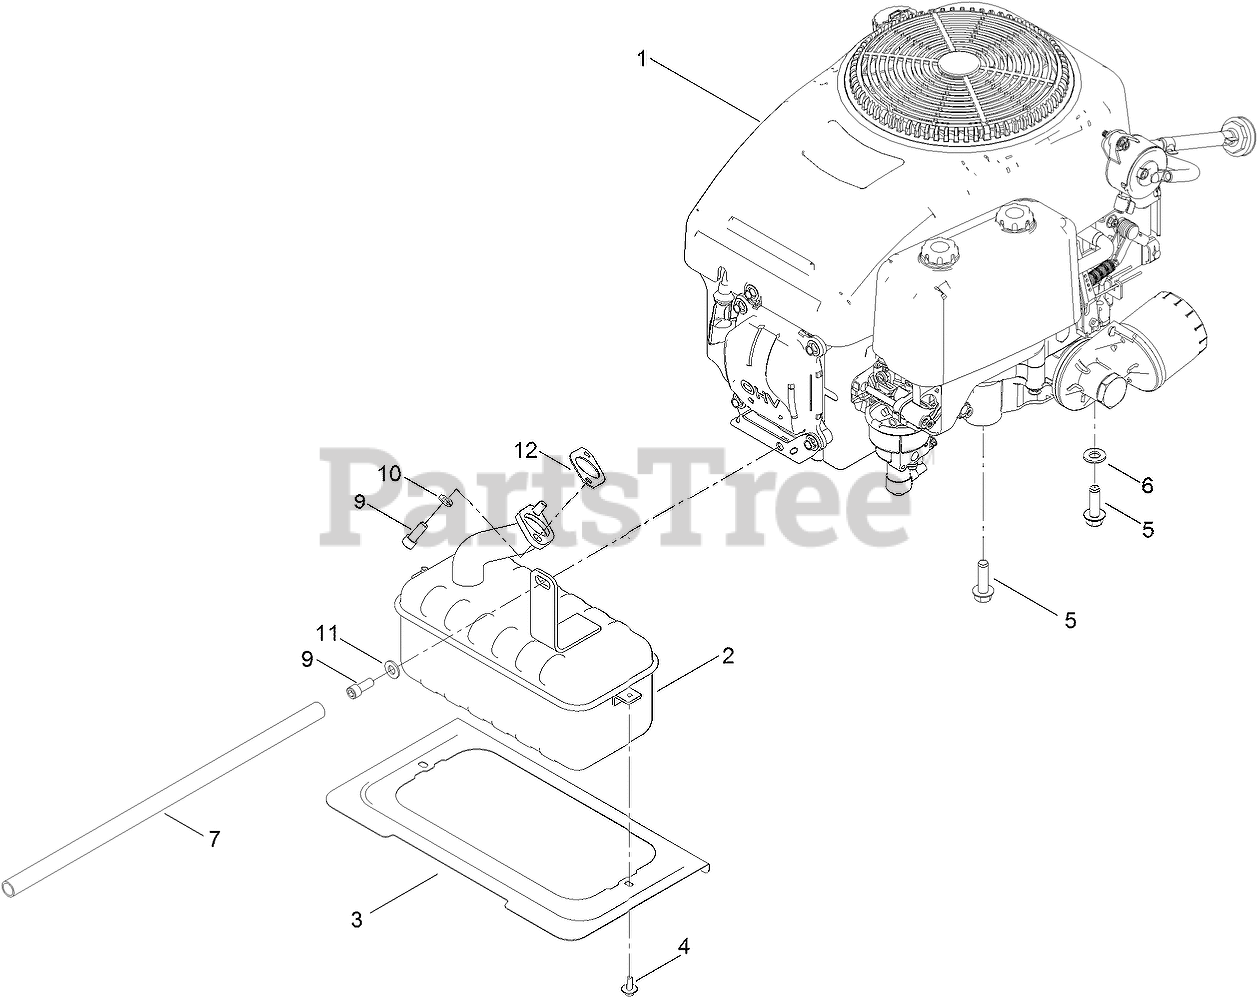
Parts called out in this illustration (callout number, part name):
1	ENGINE-LC1P92F-1
2	MUFFLER
3	SHIELD-HEAT
4	SCREW-HWH, THD ROLL
5	SCREW-HWH, THD ROLL
5	SCREW-THD
6	WASHER-FLAT
7	TUBE-DRAIN, OIL
9	SCREW-HSH
10	WASHER-LOCK
11	WASHER-PLAIN
12	GASKET-EXHAUST
